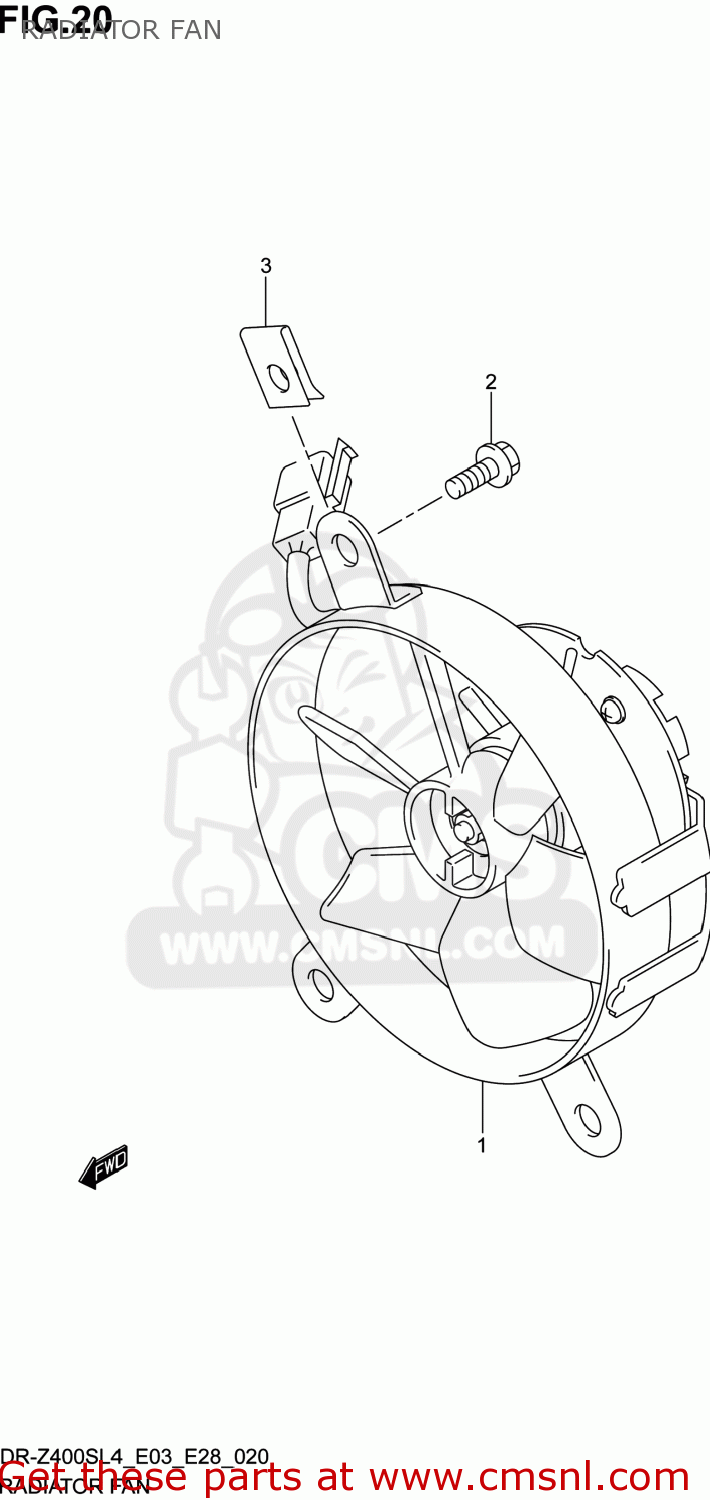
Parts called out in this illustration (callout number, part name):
1	FAN ASSY,RADIATOR
2	BOLT
3	NUT
